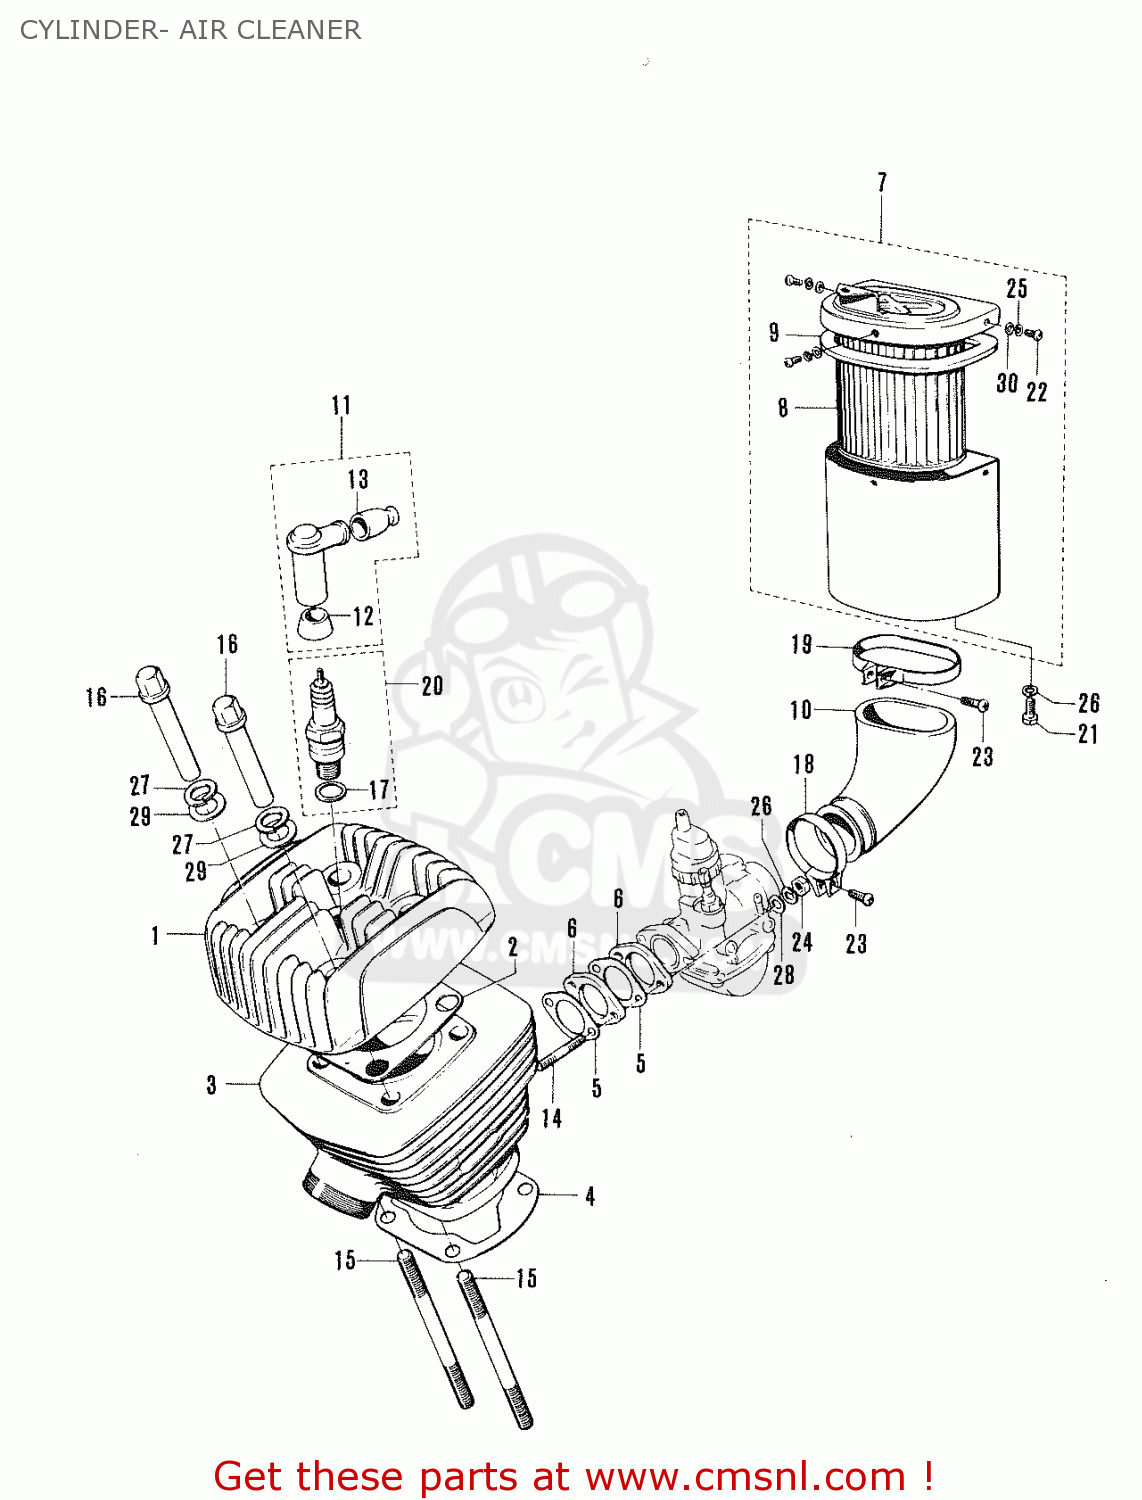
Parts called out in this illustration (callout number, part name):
1	HEAD,CYLINDER
2	GASKET,CYLINDER HEAD (A (NAS)
3	CYLINDER
4	GASKET,CYLINDER (MCA)
5	GASKET,CARBURETOR (NAS)
6	INSULATOR,CABURETOR
7	CLEANER ASSEMBLY,AIR
8	FILTER,AIR CLEANER
9	AIR CLEANER GASKET
10	TUBE,AIR CLEANER OUTLET
11	CAP,SPARK PLUG
12	SEAL,SPARK PLUG
13	SPARK PLUG CAP HIGH TENSION CORD SEAL
14	STUD
15	STUD
16	NUT
17	GASKET(14X19.2X2) (NAS)
18	CLAMP
19	CLAMP
20	SPARK PLUG
21	HEXAGON BOLT
22	CROSS HEAD SCREW
23	SCREW
24	NUT
25	LOCK WASHER
26	LOCK WASHER
27	WASHER,LOCK 12
28	WASHER 6MM
29	WASHER
30	WASHER
